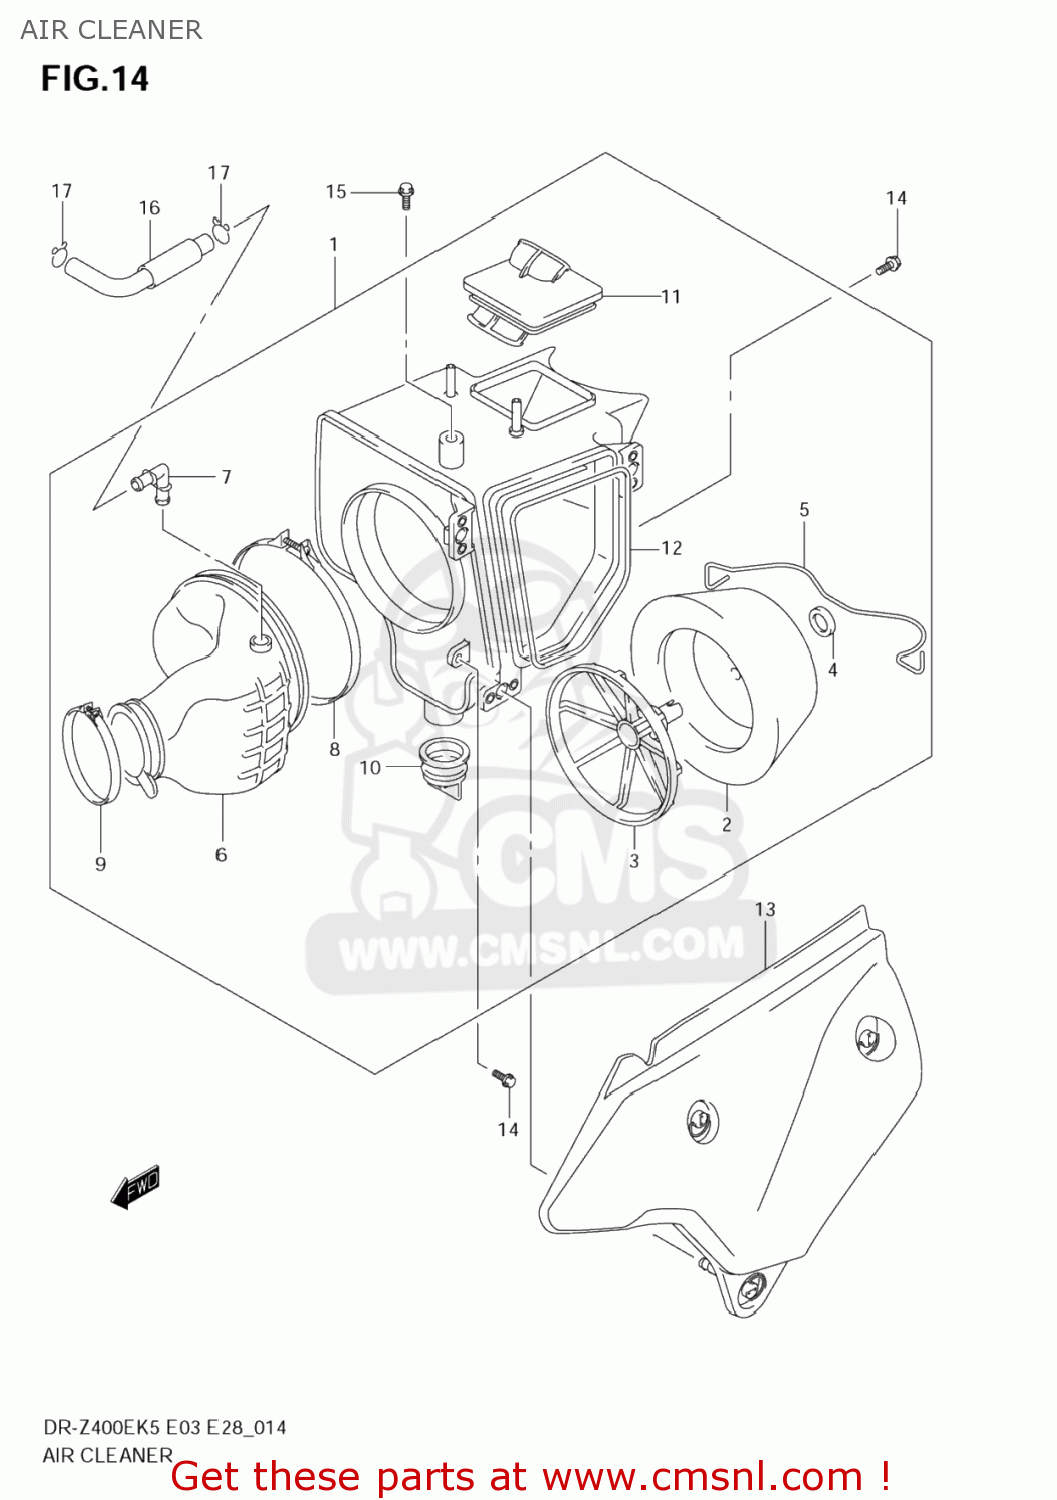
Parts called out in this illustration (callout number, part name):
1	CLEANER,AIR
2	FILTER ASSY
3	HOLDER,FILTER
4	SPACER
5	SPRING
6	TUBE,OUTLET
7	JOINT
8	CLAMP
9	CLAMP
10	VALVE
11	TUBE,INLET
12	GASKET,AIR CLEANER (NAS)
13	CAP,AIR CLEANER
14	BOLT
15	BOLT(6X14.6)
16	TUBE,BREATHER
17	CLIP
